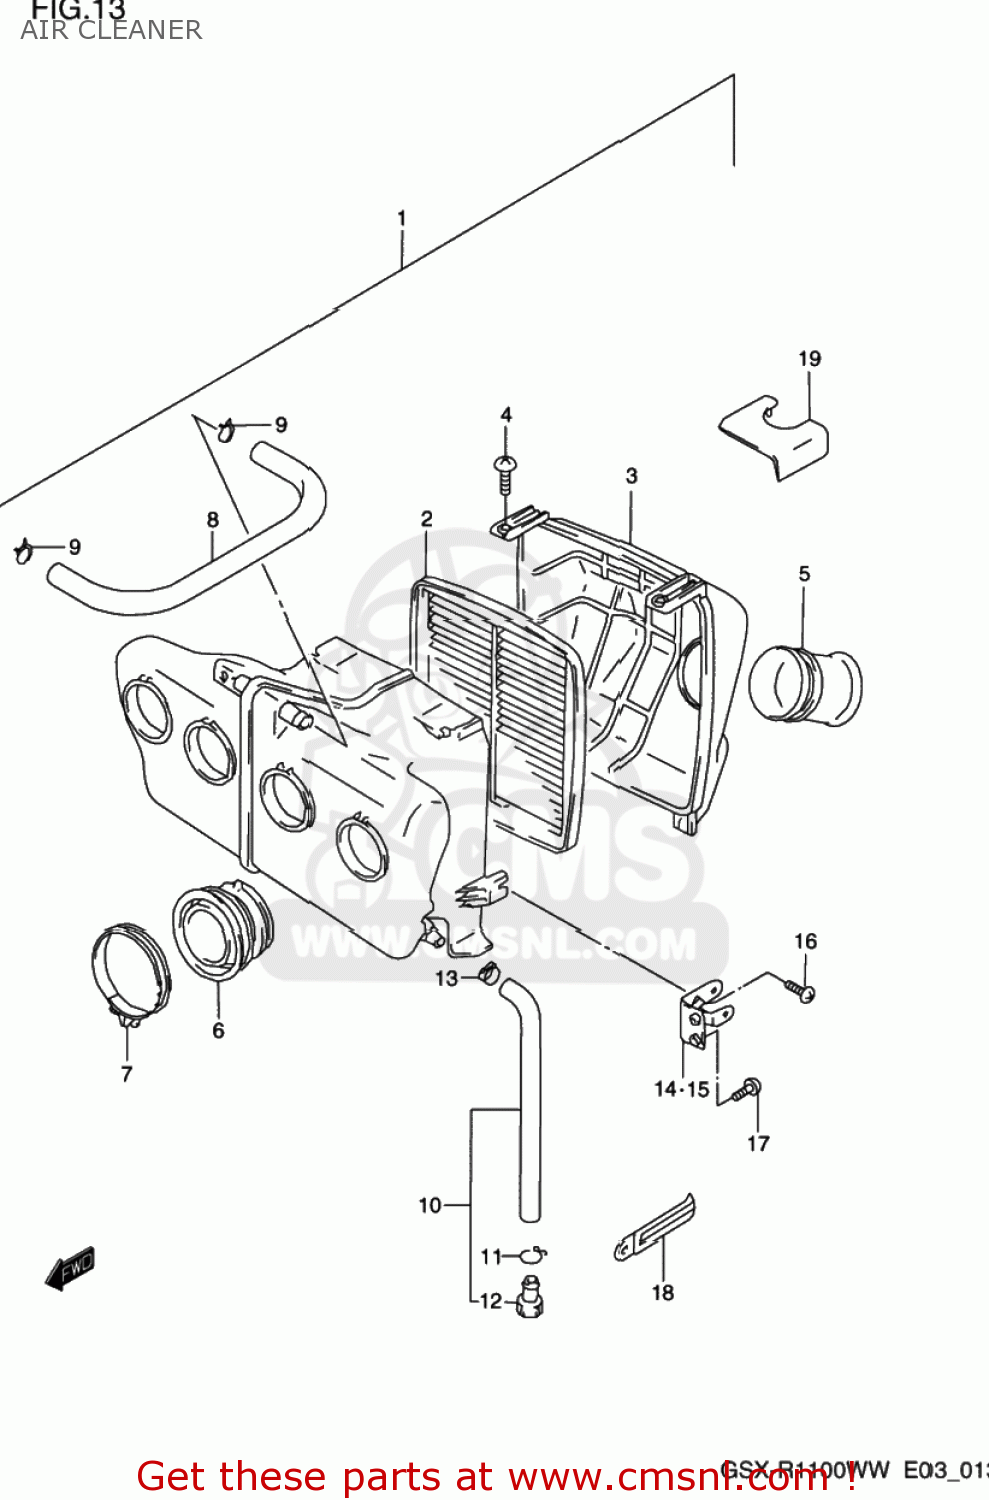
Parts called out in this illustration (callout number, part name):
1	CLEANER ASSY,AIR
2	FILTER,AIR
3	CAP,AIR CLEANER
4	SCREW 5X12
5	TUBE,INLET
6	TUBE,OUTLET
7	CLAMP
8	TUBE,BREATHER
9	CLIP
10	TUBE,DRAIN
11	CLIP
12	STOPPER,DRAIN
13	CLIP
14	BRACKET COMP,AIR CLEANER
15	BRACKET COMP,AIR CLEANER
16	SCREW
17	SCREW
18	CLAMP
19	COVER,AIR CLEANER
